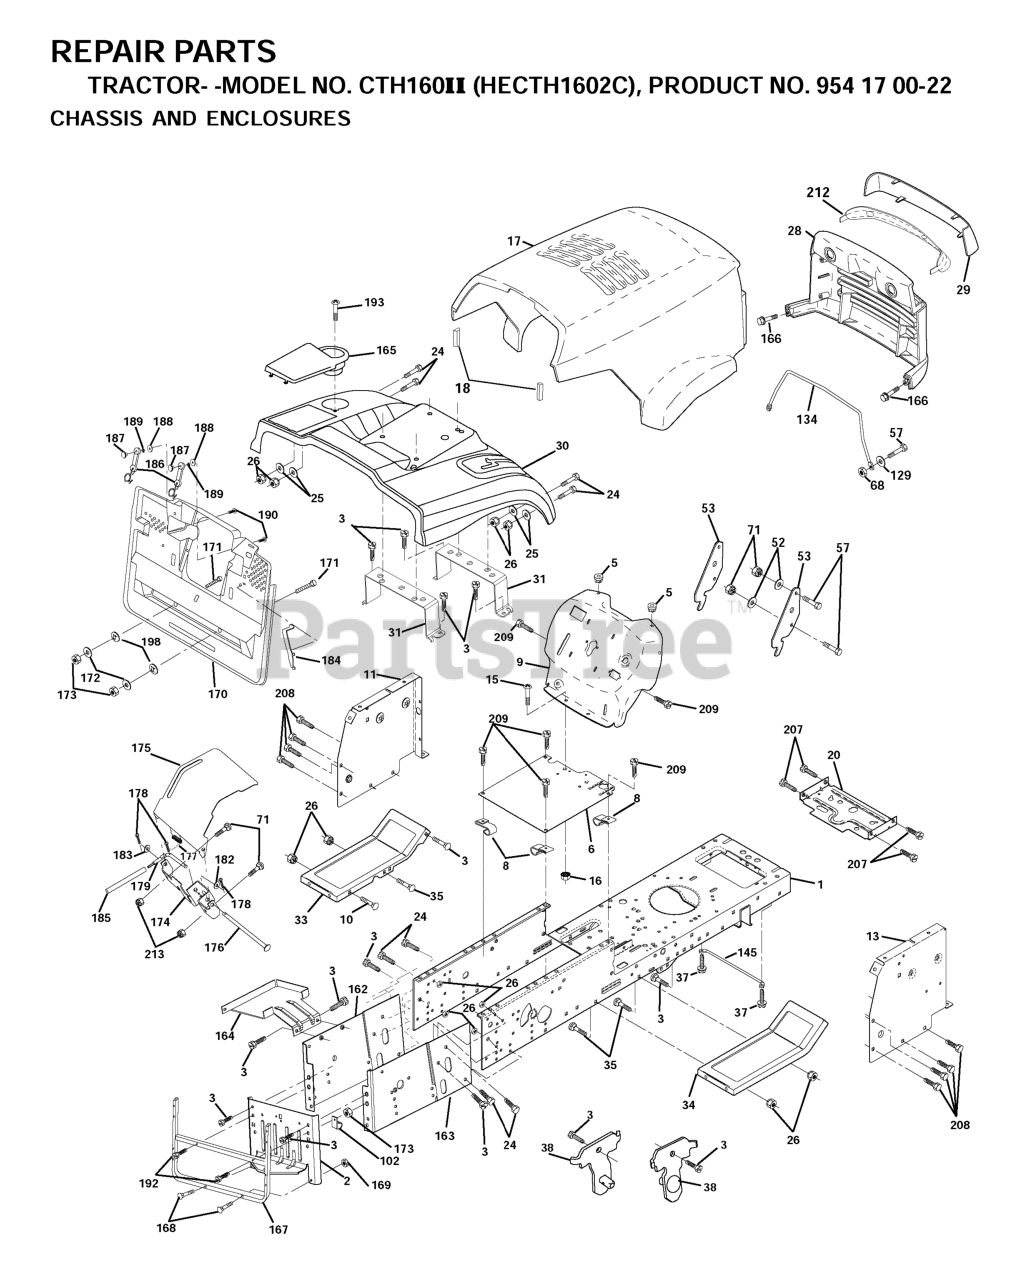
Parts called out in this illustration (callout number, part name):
1	CHASSIS STAMPING
3	SCREW 3/8-16X3/4
5	BUMPER.RUBBER.HOOD
6	SADDLE FLAT
8	CLIP,INSULATOR
10	BOLT D
11	PANEL DASH LH
13	DASH PANEL RH
15	Screw, Machine, Truss Head 5/16-18 UNC x 3/4
16	NUT
17	HOOD
18	BUMPER HOOD T
20	PLATE MTG
25	WASHER
26	NUT
28	GRILL
29	LENS
30	FENDER.CRD.ORANGE
31	BRACKET SUPPORT FENDER
33	FOOT REST LH
34	FOOTREST RH
37	Screw 5/16-18 x 1/2 Hex, Self Tapping 5/16-18 x 1/2
38	BRACKET
53	BRACKET PNT PICK OFF LT/PL
57	BOLT
68	NUT
71	NUT.CROWNLOCK.1/4
102	CLIP T
134	ROD SUPPORT HOOD LT/PL HUS.
145	ROD PIVOT CHASSIS/HOOD
162	Bracket Exten Chassis Lh CRD
165	COVER BATTERY
166	SCREW
167	SUPPORT.ASM.BACKPLATE
168	BOLT.ROUND.HEAD.SQUARE.NECK
169	NUT T
170	BACKPLATE ASM
172	WASHER
176	HINGE PIN
177	SPRING COVER LH
178	COTTER PIN
180	BOLT RB
181	LOCKNUT
183	WASHER
184	BRACKET.ACTUATOR.BAGGER.SRD
185	TUBE LEVER
186	LATCH ASSY
187	WELDNUT
189	LOCKWASHER #10
190	SCREW
192	SCREW LT
193	Screw Truss 1/4-20 x 3/4 Tap/R
207	SCREW, 5/16-18 X 1/2
208	SCREW 3/8-16X1/2
209	SCREW, 3/8-16X3/4
212	INSERT LENS REFLECTOR
